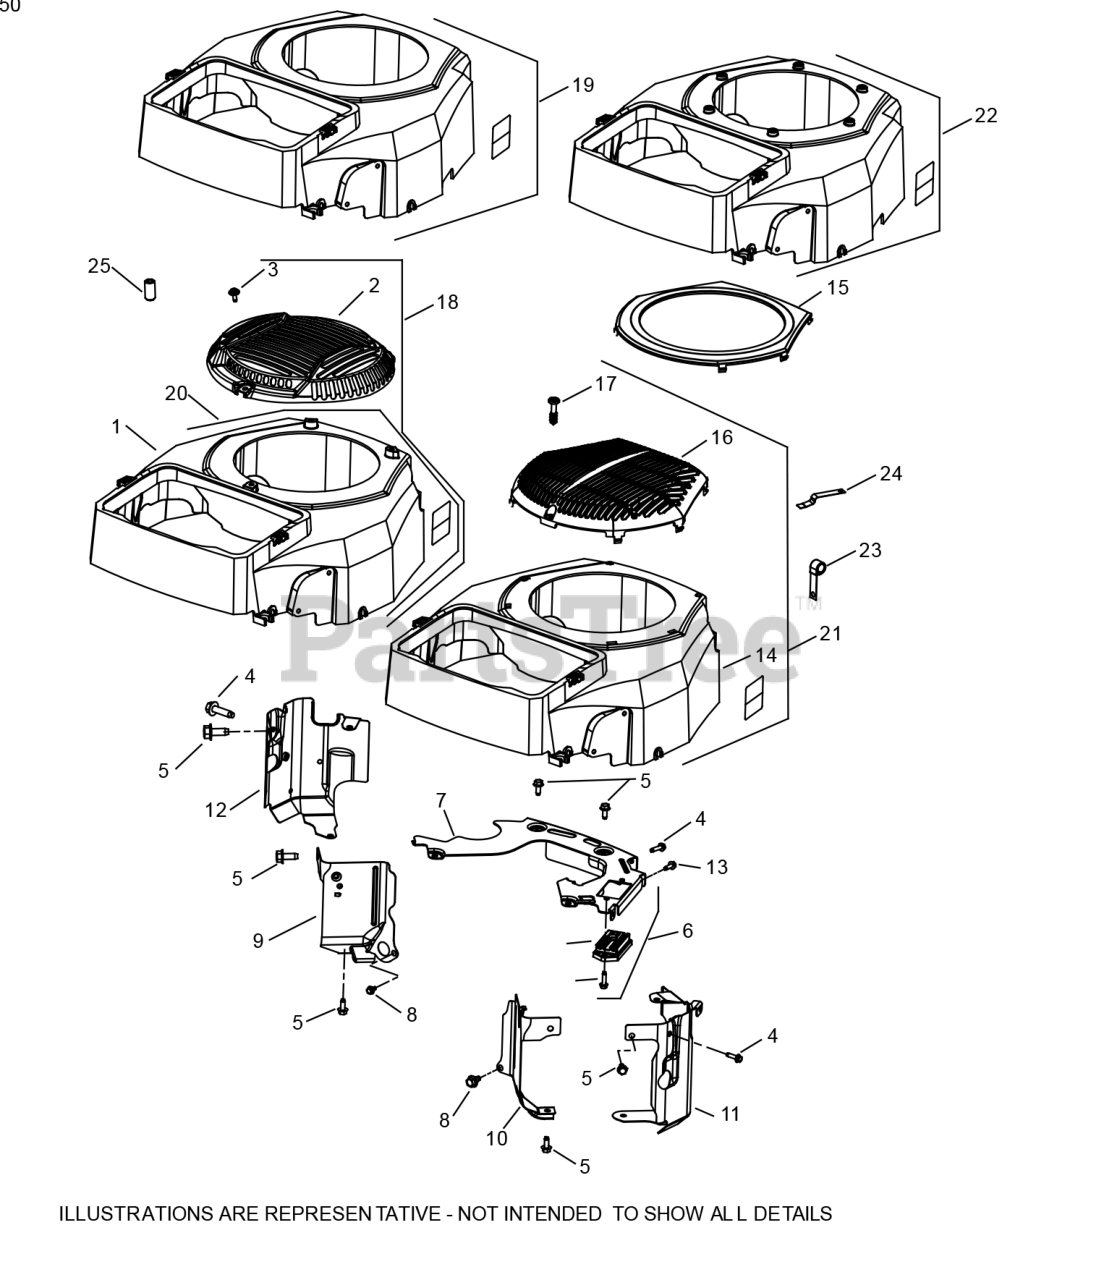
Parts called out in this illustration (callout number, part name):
1	BLOWER HOUSING KIT
2	GUARD-GRASS SCREEN (METAL)
4	THREAD FORMING SCREW
5	SCREW-THREAD FORMI
7	PLATE-BACKING
9	BAFFLE #1 VALLEY
10	BAFFLE #2 VALLEY
11	LEFT BARREL BAFFLE
12	RIGHT BARREL BAFFLE
13	THREAD FORMING SCREW
